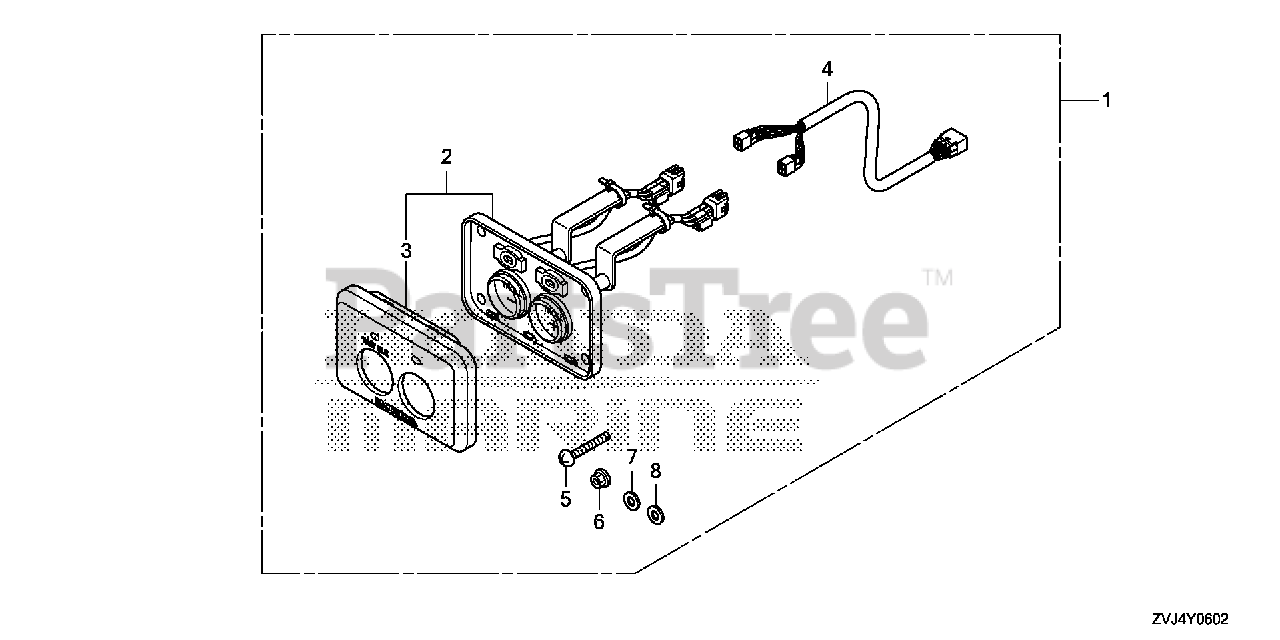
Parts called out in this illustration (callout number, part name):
1	PANEL KIT, FUNCTION SWITCH
2	PANEL ASSY., FUNCTION SWITCH
3	PANEL, FUNCTION SWITCH
4	SUB-HARNESS ASSY., FUNCTION SWITCH
5	SCREW, PAN (5X40) DUAL QTY = (8) (SINGLE)
6	NUT, FLANGE (5MM)
7	WASHER, PLAIN (5MM)
8	WASHER, SPRING (5MM)
